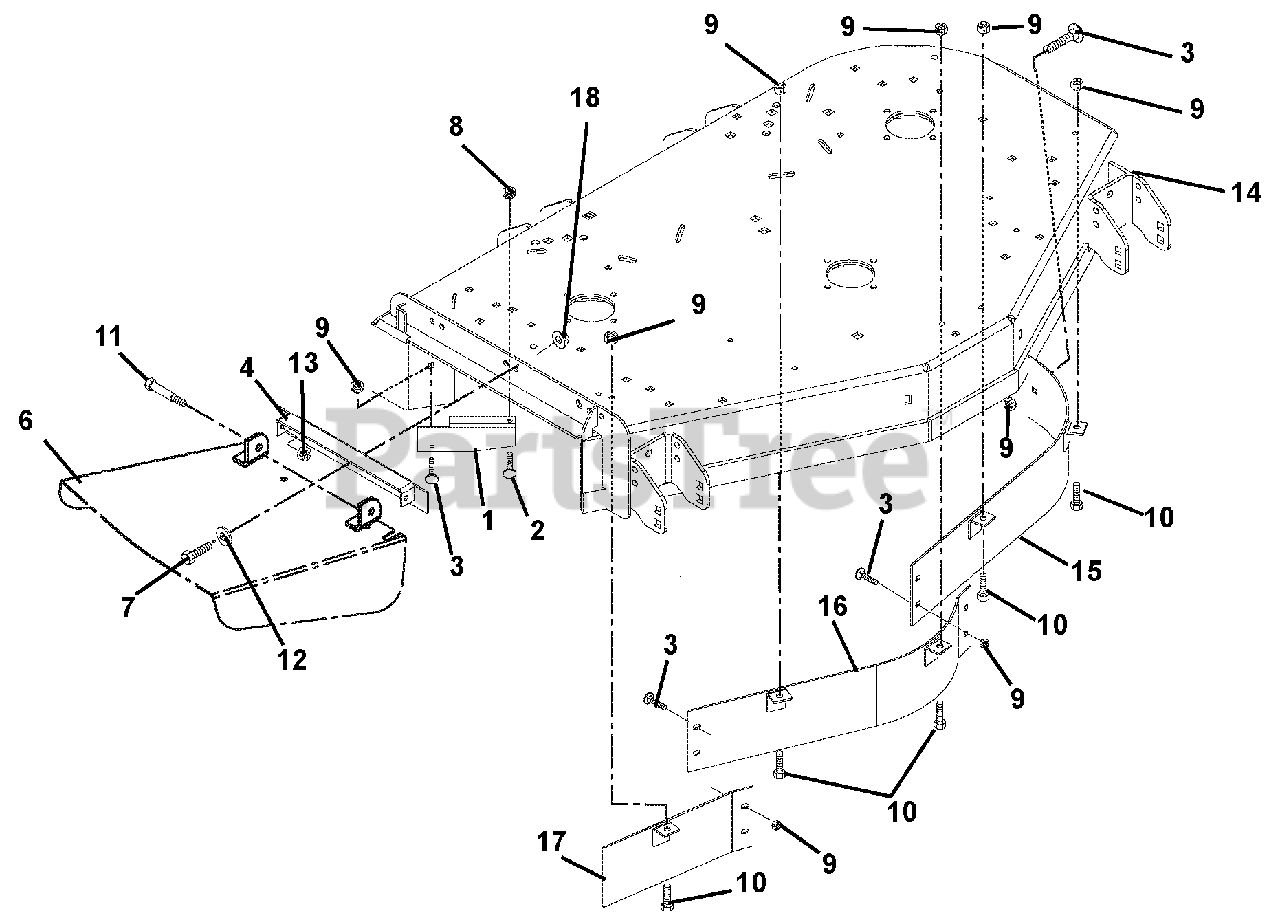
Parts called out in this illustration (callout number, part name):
1	Deflector- 72 in. (086, 091, 107)
2	Bolt-Round Head Square Neck .38-16 x .75 Grade 5
3	Bolt-Round Head Square Neck .31-18 x .75 Grade 5
4	Weldment, Discharge Chute Bracket (045, 052, 066, 071, 084, 087, 102, 103, 104)
5	Weldment, Discharge Chute Bracket (046, 047, 067, 068, 085, 086, 088, 089, 091, 105, 106, 107)
6	Chute-Discharge (045, 052, 066, 071, 084, 087, 102, 103, 104)
7	Bolt-Hex .38-16 x 1.00 Grade 5
8	Nut-Locking-Top-Flange .38-16
9	Nut, Locking-Top-Flange .31-18
10	Bolt, Hex .31-18 x .75 Grade 5
11	Bolt, Shoulder .38-16 x .50 Socket Head
12	Washer, Flat Steel .38 x .875 x .083 (045, 052, 066, 071, 084, 087, 102, 103, 104)
13	Nut, Locking-Center .38-16
14	Weldment, 52 in. Mower Deck (045, 052, 066, 071, 084, 087, 102, 103, 104)
15	Weldment, Upper Baffle Left 52 in. (045, 052, 066, 071, 084, 087, 102, 103, 104)
16	Weldment, Baffle, Center Front 52 in. (045, 052, 066, 071, 084, 087, 102, 103, 104)
17	Weldment, Baffle, Right Front 52 in. (045, 052, 066, 071, 084, 087, 102, 103, 104)
18	Nut, Flange .375-16
